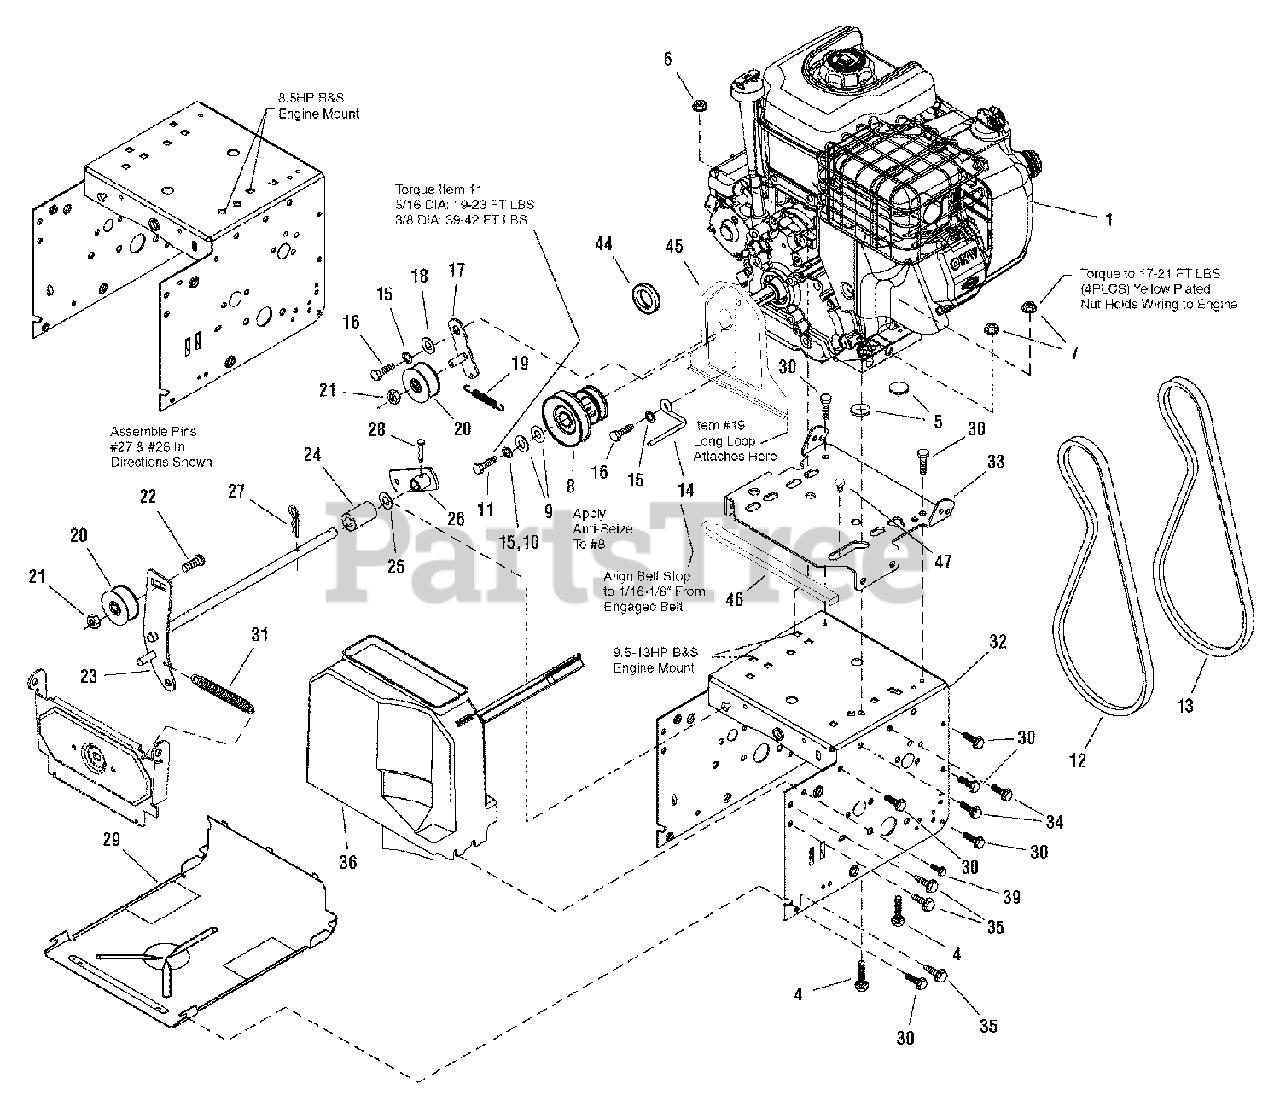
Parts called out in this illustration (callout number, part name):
4	CARRIAGE BOLT, 3/16-18 x 1-1/2
5	NUT, Speed
6	NUT, Hex Flange 5/16-18 Whiz Lock
7	NUT, Hex Flange 5/16-18 ESNA
8	PULLEY, Engine
9	WASHER, 3/16
9	WASHER, 3/8
10	LOCKWSHER, Spring 3/8
11	CAPSCREW, Hex Head 3/8-24 x 1-1/4 G5
11	CAPSCREW, Hex Head 3/16-24 x 1-1/4 G5
12	V-BELT, 3L 33.13, Drive
13	V-BELT, 4L 36.5, Auger
13	V-BELT, 4L 38.5, Auger
14	STOP, Belt
15	LOCKWASHER, Spring 3/16
16	CAPSCREW, Hex Head 5/16-24 x 3/4 G5
17	IDLER BRACKET ASSEMBLY, Drive Belt
18	BUSHING, Idler Bracket
19	SPRING, Extension Idler
20	IDLER, Plastic Ball Bearing
21	NUT, Hex Centerlock Jam 3/8-16
22	CARRIAGE BOLT, 3/8-16 x 1-1/4
23	IDLER ASSEMBLY, Auger
24	SPACER/AUGER BRACKET
25	WASHER, 1/2
26	BRACKET & HUB ASSEMBLY, Spring
27	PIN, Hair
28	PIN, Clevis
29	PANEL, Bottom
30	SCREW, Hex Washer Head Taptite 1/4-20 x 5/8
31	SPRING, Extension Auger Idler
32	FRAME BOX, 7.5-8.5HP
32	FRAME BOX, Steerable
33	PLATE, Engine Mount
34	SCREW, Hex Washer Head Taptite 5/16-18 x 1/2
35	SCREW, Hex Washer Head Taptie 5/16-18 x 3/4
36	COVER, Belt w/Toolbox B&S
39	SCREW, 1/4-AB x 3/4 Hex
44	SHAFT, Seal
45	SEAL, Plate
46	SEAL, Strip
47	CLIP, Pine Tree
